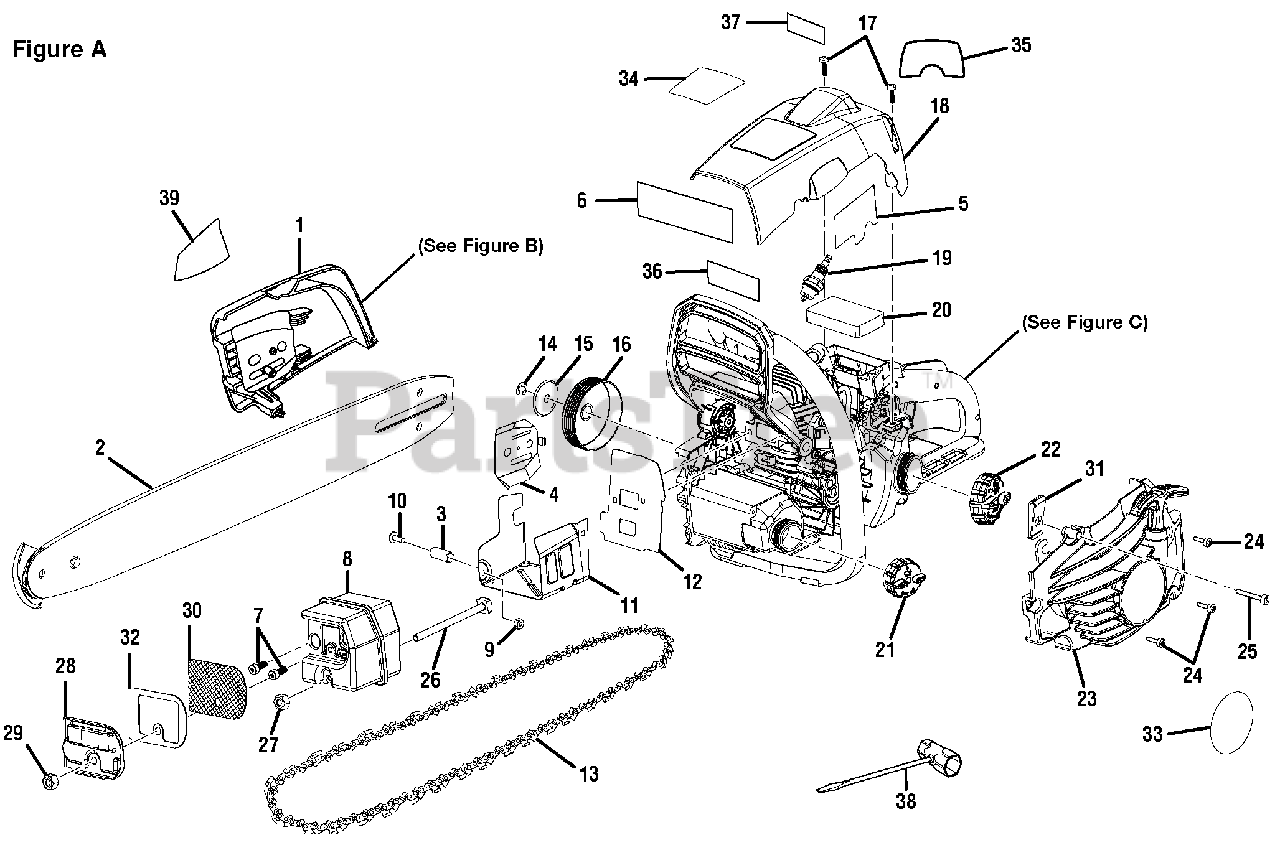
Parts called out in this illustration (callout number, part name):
1	Chain Cover Assembly
2	Guide Bar with SAFE-T-TIP: UT10640 - 14 in
4	Inner Guide Plate
5	Heat Shield Tape
6	Heat Shield Tape
7	Screw (1/4-20 x 5/8 in.)
8	Muffler Assembly
9	Lock Nut (10-24)
10	Screw (10-24 x 5/8 in.)
11	Heat Shield
12	Muffler Gasket
13	Chain (3/8 in.): UT10640 - 52 link, 14 in
14	E-Clip
15	Clutch Washer
16	Sprocket Drum and Bearing Assembly
17	Screw (10-16 x 16 mm)
18	Cylinder Cover
19	Spark Plug (Champion RCJ4)
20	Air Filter
21	Oil Cap Assembly
22	Fuel Cap Assembly
23	Starter Cover Assembly
24	Screw (M4 x 17 mm)
25	Screw (#10-16 x 24 mm, T25 Torx)
26	Screw (#10-32 x 2.8 in.)
27	Nut (#10-32)
28	Exhaust Cover
29	Nut, Muffler (M5)
32	Exhaust Cover Gasket
33	Starter Cover Labels: UT10640 - 42cc
34	Warning Labels: UT10640 - 42cc
35	Starting Instruction Label
36	Chain Brake Label
37	Warning Label (Combustion)
38	Combination Wrench
39	Chain Cover Labels: UT10640 - 42cc
